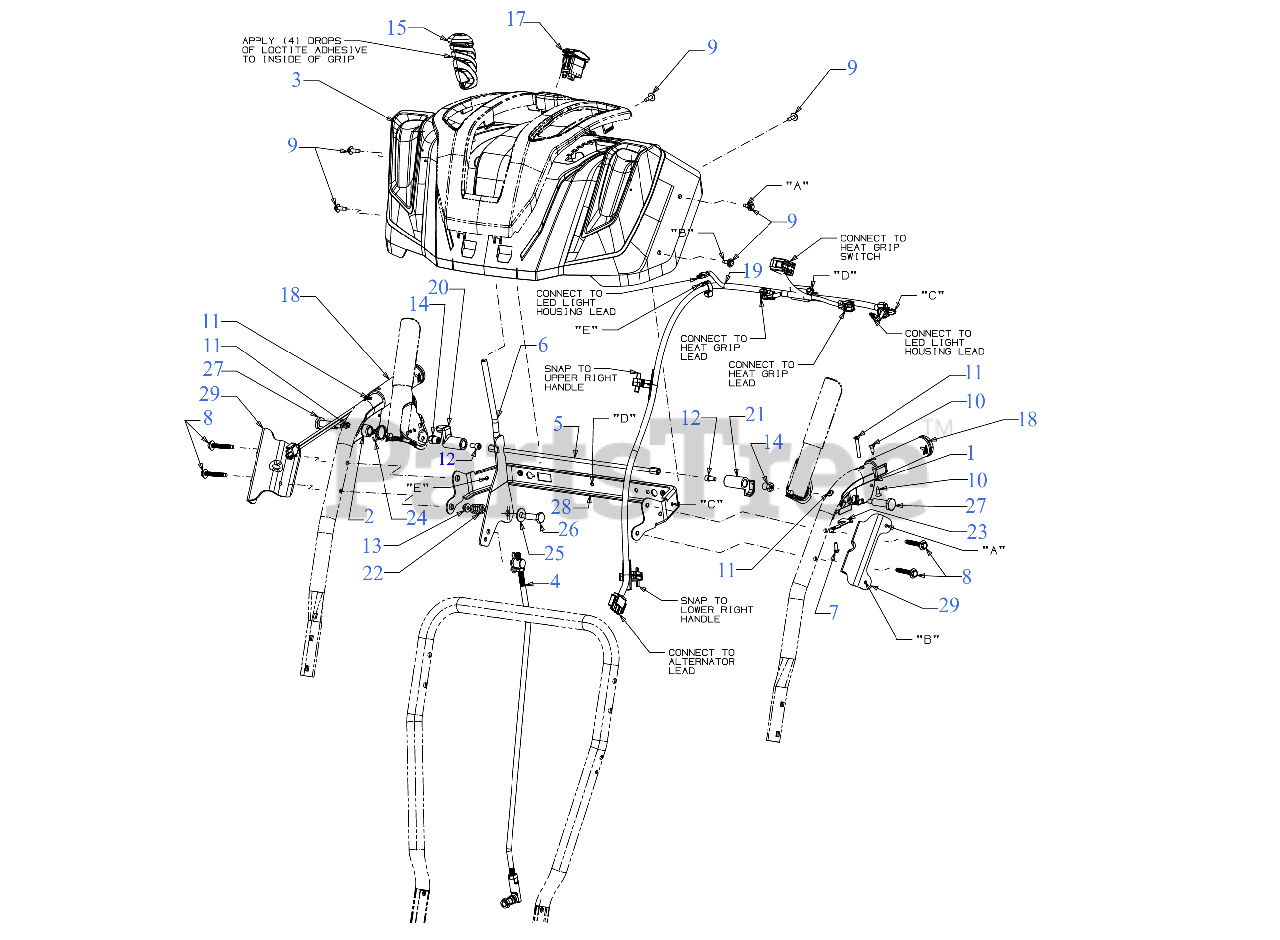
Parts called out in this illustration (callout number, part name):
1	CLUTCH LOCK HANDLE ASSEMBLY (LH)
2	CLUTCH LOCK HANDLE ASSEMBLY (RH)
3	HANDLE PANEL ASSEMBLY
4	SHIFT ROD ASSEMBLY
7	SCREW #8-16 x .50
8	SCREW 1/4-20 x 1.625
9	SCREW M6-1 x .625
10	SCREW #10-16 x .625
11	SCREW #10-24 x 1.375
12	SCREW 1/4-20 x .50
13	FLANGE LOCK NUT
14	HEX NUT W/PATCH
15	PTO HANDLE GRIP .355 ID
17	HEATED GRIP SWITCH
18	HARNESS-SNOW HEATED GRIP RED
19	HARNESS (TWO HEADLIGHT)
21	CLUTCH LOCK CAM
22	COMPRESSION SPRING
23	CLUTCH SPRING
24	TORSION SPRING
25	FLAT WASHER .40X.88X.060
26	SHOULDER SCREW
27	SHOULDER SCREW .437 x 1.345 1/4-20
